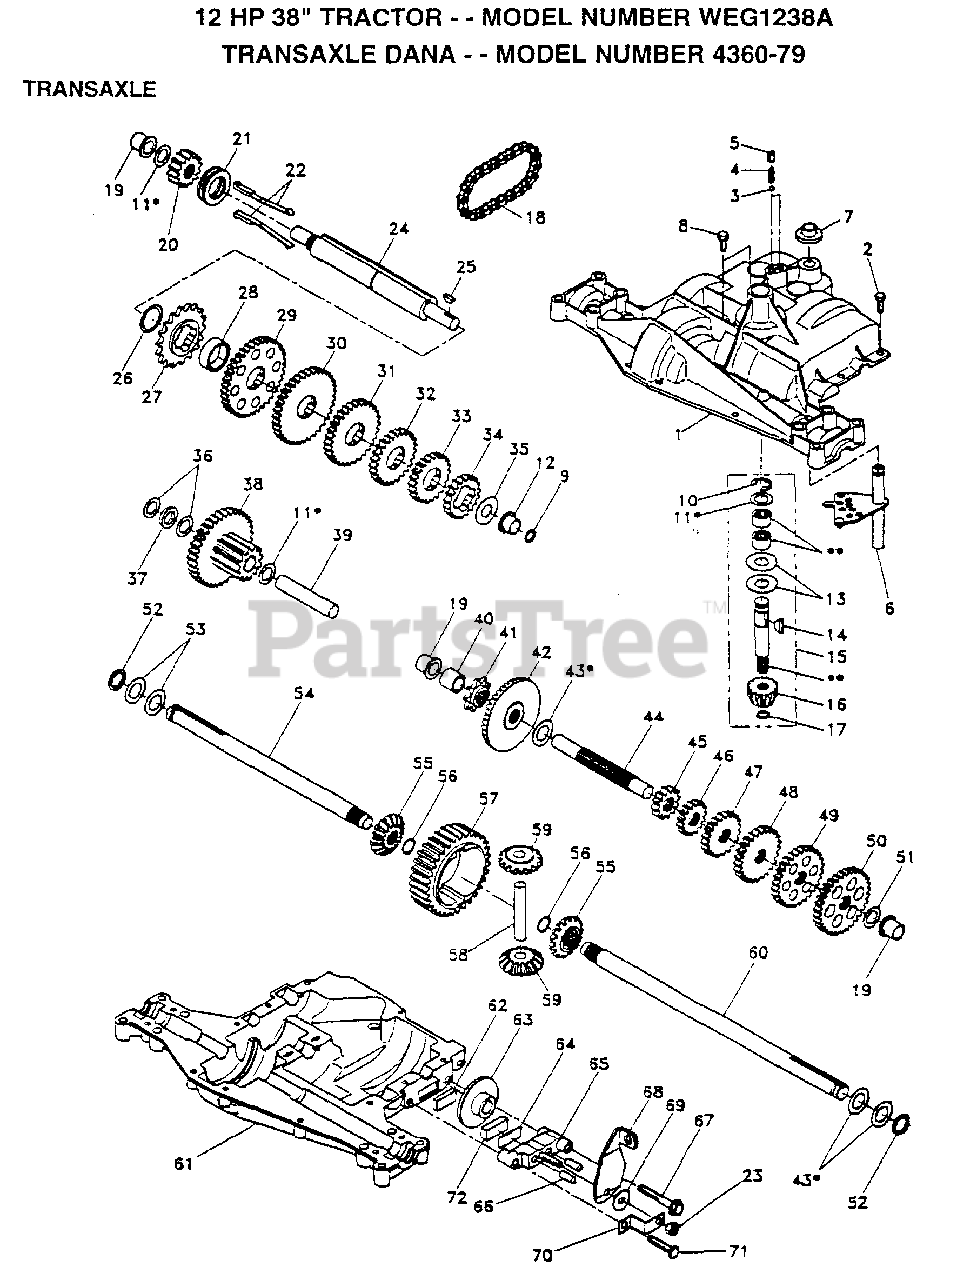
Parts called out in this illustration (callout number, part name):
1	HOUSING UPPER TRN
4	"SPRING, DETENT LT"
5	"SCREW, SET LT"
6	KIT SHIFTER ASM
7	SHIFTER BOOT
8	SCREW TAP W/SEAL
9	SQUARE RING
11	ASM KIT SHIM 4689
12	BEARING FLAN-DANA
13	WASHER T
14	KEY WOODRUFF-DANA
15	AS KIT INPUT SHFT
16	PINION 14T T
17	"RING,RETAINING LT"
18	"CHAIN,24 PTCH LT"
19	BEARING.FLNG.5510
20	GEAR SPUR 14 TTH
21	COLLAR CLUTCH
22	ASM KIT CLTCH KEY
23	NUT.LOCK.5/16-24
24	SHAFT INTERM DANA
25	WOODRUFF KEY
26	"RING,RETAINING LT"
27	SPROCKET 18T T
28	SPACER YT
29	GEAR SPUR 37 TTH
30	GEAR SPUR 35 TTH
32	GEAR 25T LT
33	GEAR SPUR 22 TT
34	SPUR GEAR 19T
35	"WASHER, PLAIN LT"
36	WASHER 025
37	SPACER
38	ASSM GEAR COMB
39	SHAFT IDLER
40	SPACER T
41	SPROCKET 9T LT
43	ASM KIT SHIM
44	SHAFT T
45	GEAR SPUR 12 TTH
46	GEAR SPUR 15 TTH
48	"GEAR, SPUR 25T LT"
49	GEAR 28T T
50	"GEAR, SPUR 31T LT"
51	WASHER 060
52	NEOPRENE WASHER
53	WASHER 031
55	GEAR 15T T
56	"RING,RETAINING LT"
58	SHAFT T
59	GEAR 1ST T
61	HOUSING LOWER TNS
62	PUCK T
63	BRAKE DISC. T
64	SPACER LT
66	PIN T
69	WASHER LT
71	"SCREW, TAPPING LT"
72	PUCK T
